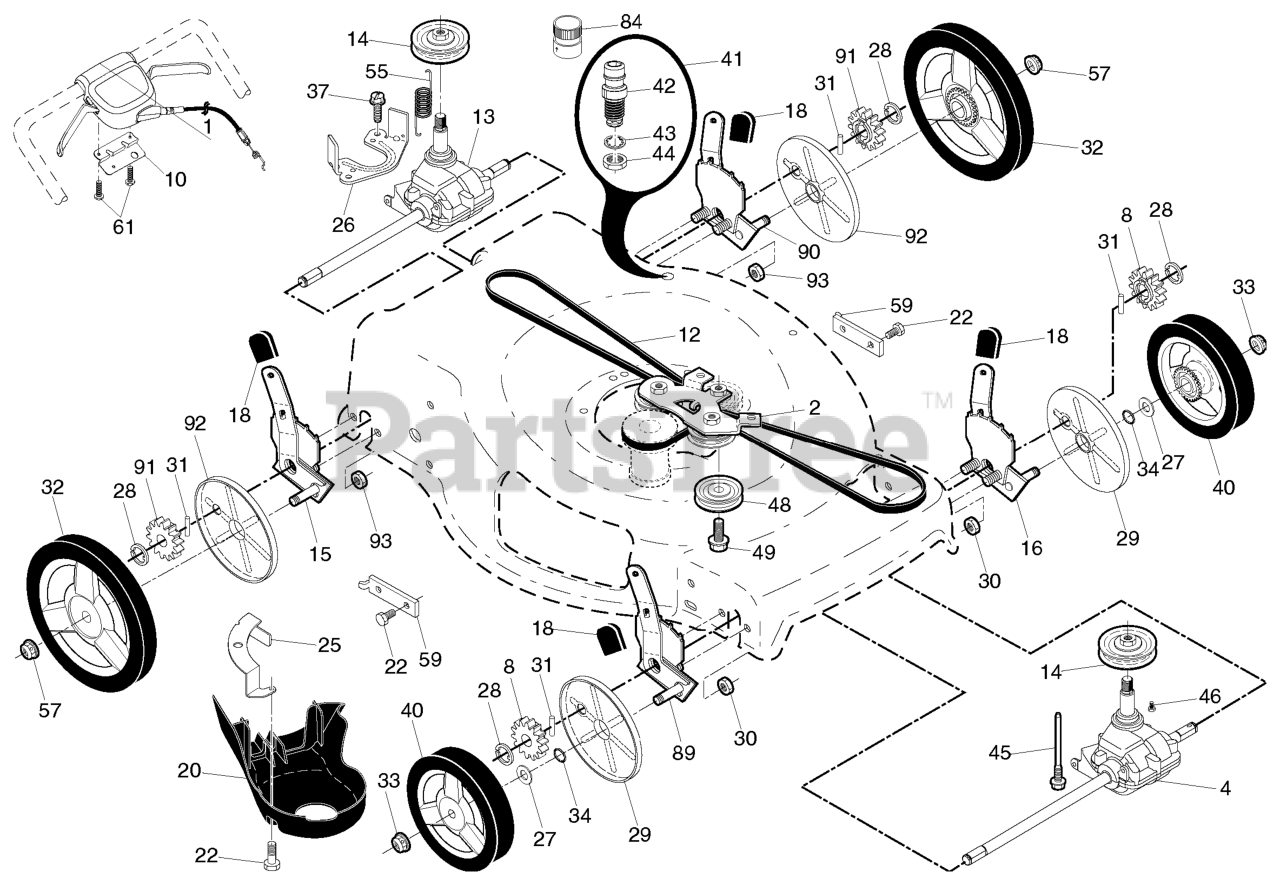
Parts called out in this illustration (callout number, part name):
1	CONTROL.AWD.DT.BS
2	BRACKET.ASM.AWD.BZP.BLACK
4	TRANSMISSION.22+.AWD.FRT
8	PINIION.14.TOOTH.RGD
10	BRACKET DUAL TRIGGER CONTROL
12	BELT.DRIVE.AWD.13 ZINC DUSTED
13	TRANSMISSION.22+AWD.WALK.MOWER
14	PULLEY.DRIVE.SM.AWD/RWD
15	ADJUSTER.ASM.HW.AWD.QK.RR.BLKZ
16	ADJUSTER.ASM.22+FGD.LF /AWD LT
18	SELECTOR KNOB
20	COVER.REAR.DRIVE.22+2013
22	BOLT.5/16HEX.WHS.HD
25	BRACKET.DRIVE.COVER.RGD.BZP
26	BRACKET.TRAN.BELTKEEPER.22+RGD
27	WASHER FLUT
28	E-RING 7/16 RE
29	COVER.DUST.WHEEL.INNER.WALK
30	NUT.FLANGE.1-4-20-SERR
31	PAWL, DRIVE
32	WHEEL.11.H3SP.AWD.LC.460.BB2
33	NUT.HEX.FLANGE.3/8-16.LO(3 2)
34	O-RING..070X.487.NEOPRENE
37	SCREW
40	WHEEL.8".AWD.3SP.EXT.DR.GREY
41	KIT.WASH-OUT.PORT.ZINC.WALK
42	WASHOUT.PORT.ZINC.RGD.22+
43	WASHER.LOCK.INTERNAL.TOOTH
44	LOCKNUT.HEX.WITH.O-RING
45	SCREW.HI-LO.5/16-14 X 4.10
46	SCREW.HI-LO. 5/16 X 1.00
48	PULLEY.ASM.22+ AWD
49	SCREW
55	SPRING.RETURN.AUTO.
57	NUT.HEX.FLANGE.3/8-16.LOCKNUT
59	BRACKET.SUPPORT.22+RWGD.BZP
61	SCREW, PHILLIPS HEAD 10 X 5/8
84	COUPLING.QUICK CONNECT
89	ADJUSTER.ASM.22+FGD.RF /AWD RT
90	ADJUSTER.ASM.HW.AWD.QK.LR.BZ
91	PINION.16.TEETH.HW.AWD.REAR
92	COVER.DUST.WHEEL.HW.AWD.REAR
93	NUT.HEX.FLANGE.1/4
